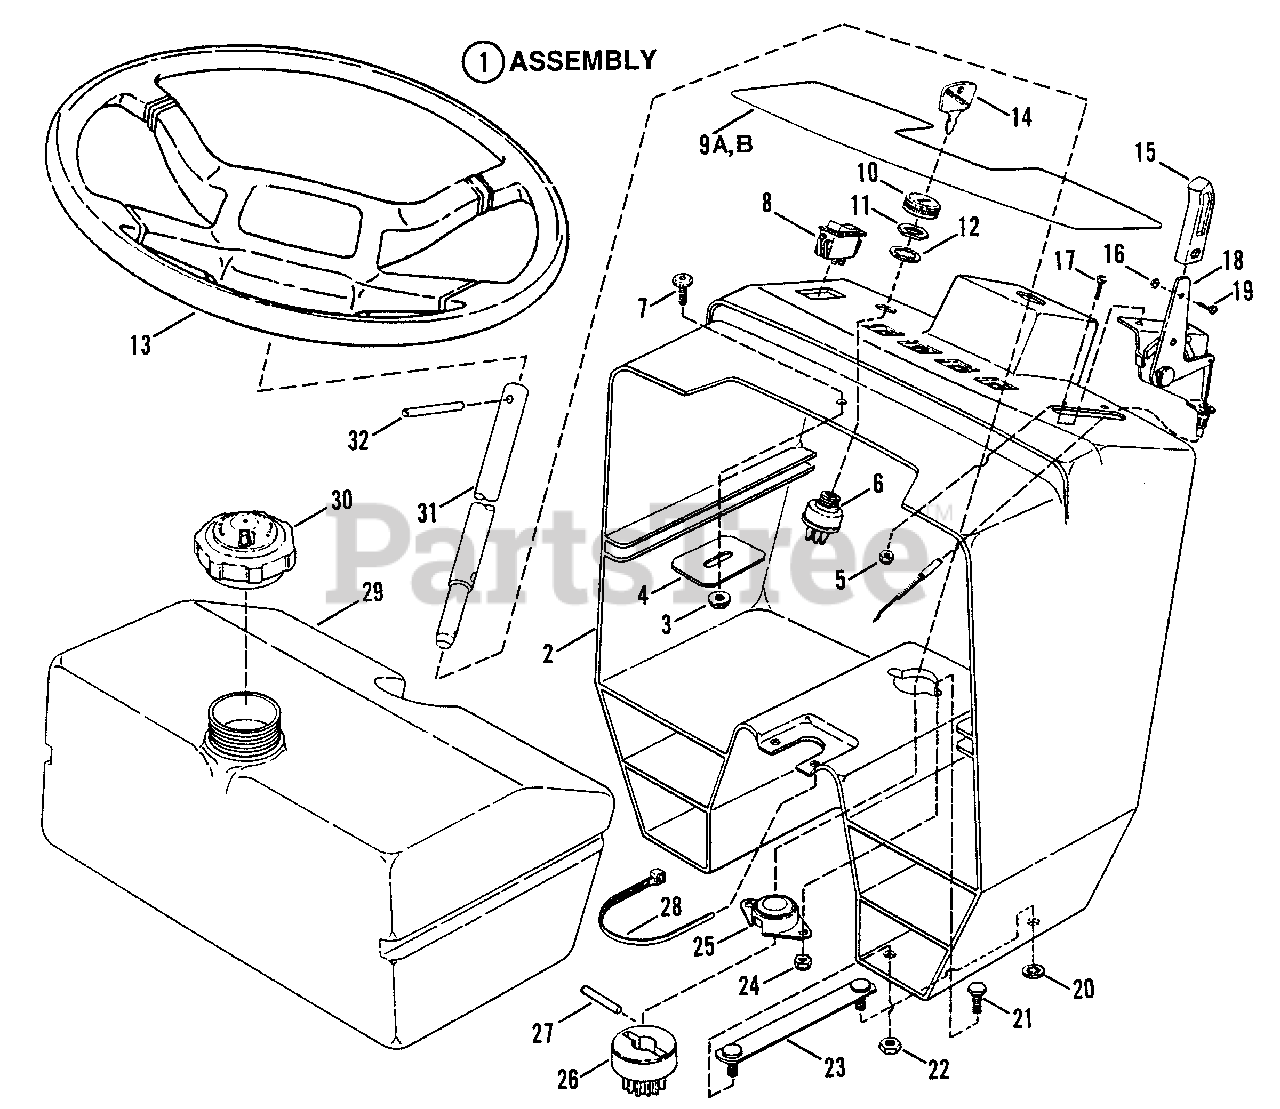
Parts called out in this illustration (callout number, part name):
1	ASSEMBLY, Console
2	CONSOLE
3	NUT, 5/16-18 Hex Flange Lock
4	BRACKET, Hood Latch Catch
5	NUT, #10-24 Hex Nyloc
6	KEYSWITCH
7	SCREW, 5/16-18 x 5/8" Torx, Truss Head
8	SWITCH, Lights
9	DECAL, Console
10	BEZEL
11	NUT, 5/8-32 Hex
12	WASHER, 5/8 Int. Tooth Lock
13	STEERING WHEEL
14	KEY, Switch (With Cover)
15	HANDLE, Throttle Control
16	NUT, #8-32 Hex
17	SCREW, #10-24 x 5/8" Machine
18	CONTROL, Throttle
19	SCREW, #8-32 x 3/8" Cross-Recessed, Fillester Head
20	RETAINER
21	SCREW, 1/4-20 x 3/4" H.H.C.
22	NUT, 5/16-18 Hex Center Lock
23	ASSEMBLY, Strap-Clinch Stud
24	NUT, 1/4-20 Hex Nyloc
25	ASSEMBLY, Flange Bearing
26	GEAR, Pinion, Steering Shaft
27	PIN, Dowel, 1/4 x 1 1/4"
28	TIE, Wire
29	ASSM'Y., Fuel Tank
30	CAP, Fuel Tank
31	SHAFT, Steering
32	ROLL-PIN
